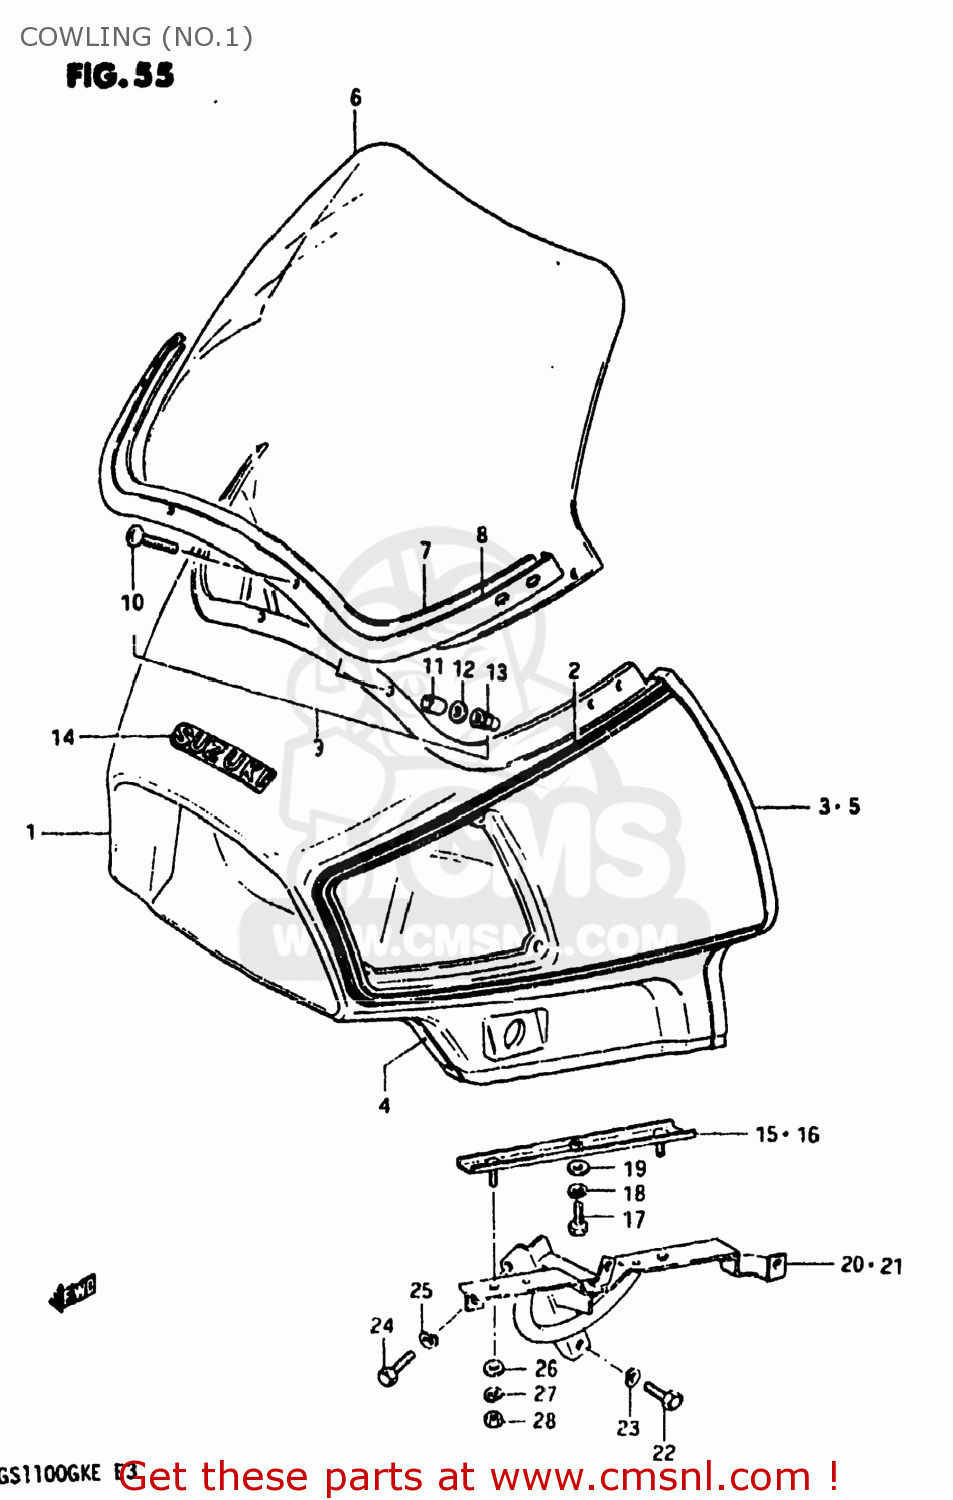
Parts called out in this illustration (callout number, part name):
1	BODY ASSEMBLY,COWLING
2	TAPE SET,COWLING
3	MOLDING,COWLING,RIGHT
4	MOLDING,LOWER
5	MOLDING,COWLING,LEFT
6	WINDSHEILD,COWLING
7	CUSHION,WINDSHEILD
8	PLATE,WINDSHEILD
9	BODY ASSEMBLY,COWLING
10	SCREW
11	SPACER(6.3X9.3X16.5)
12	WASHER (6.5X20X1.2)
13	NUT
14	EMBLEM,COWLING
15	PLATE,COWLING FITTING
16	PLATE,COWLING FITTING
17	BOLT
18	LOCK WASHER
19	WASHER
20	BRACE,COWLING
21	BRACKET,COWLING,LEFT
22	BOLT
23	LOCK WASHER
24	BOLT
25	LOCK WASHER
26	WASHER
27	LOCK WASHER
28	NUT
